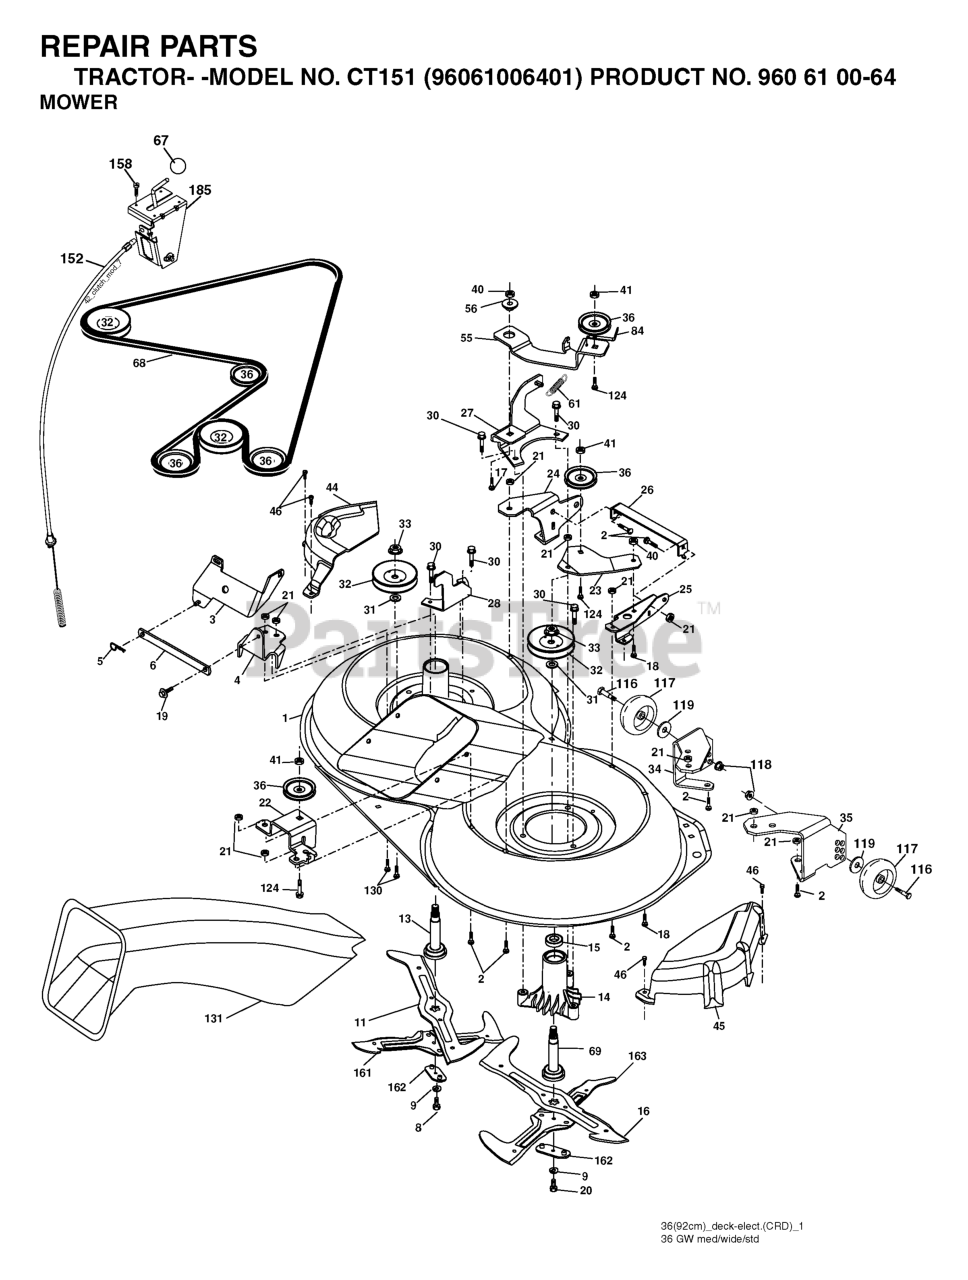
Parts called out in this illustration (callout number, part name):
2	RP BOLT 5/16-18 X3/4 ZN/YEL GR
5	RETAINER-SPRNG RB
6	BAR.SWAY.92.CRD
8	BOLT.3/8-24X1.25 GR8
9	LOCKWASHER
13	SHAFT ASM VENT
14	HOUSING.MANDREL.VENTED (MACHD)
17	BOLT.3/8-14X1.25
19	BOLT SHD 5/16-18
20	BOLT.3/8-24X1.25GR8. LHTHRD
21	LOCKNUT
26	SUPPORT
30	SCREW, WASHER HEAD
31	WASHER.SPACER.MANDREL
32	PULLEY, MANDREL
33	NUT.FLANGE.LOCK.TOP
36	PULLEY.IDLER.4.25
41	NUT LOCK FLG 3/8-16 UNC
45	COVER.MANDREL.RH.CRD
46	SCREW.1/4-20X5/8
55	ARM.IDLER.92 CRD.2006
56	SPACER.RETAINER.MOWER
61	SPRING.TENSION.BELT
67	KNOB T (3/8 HOLE)
68	BELT.DRIVE.92CM.CRD.2006
69	SHAFT.ASM.W/LWR.BRG.RH.THREAD
84	KEEPER, BELT IDLER
116	SHOULDER BOLT
117	RP WHEEL. GUAGE RALLY
118	LOCKNUT
119	WASHER.5/16.FLAT.STE.STD.
124	BOLT.3/8-16X1.50
130	BOLT.CARR.SQNK.5/16-18UNC.X3/4
131	CHUTE BAGGER
158	SCREW
185	HEAD ASM. CABLE CLUTCH
